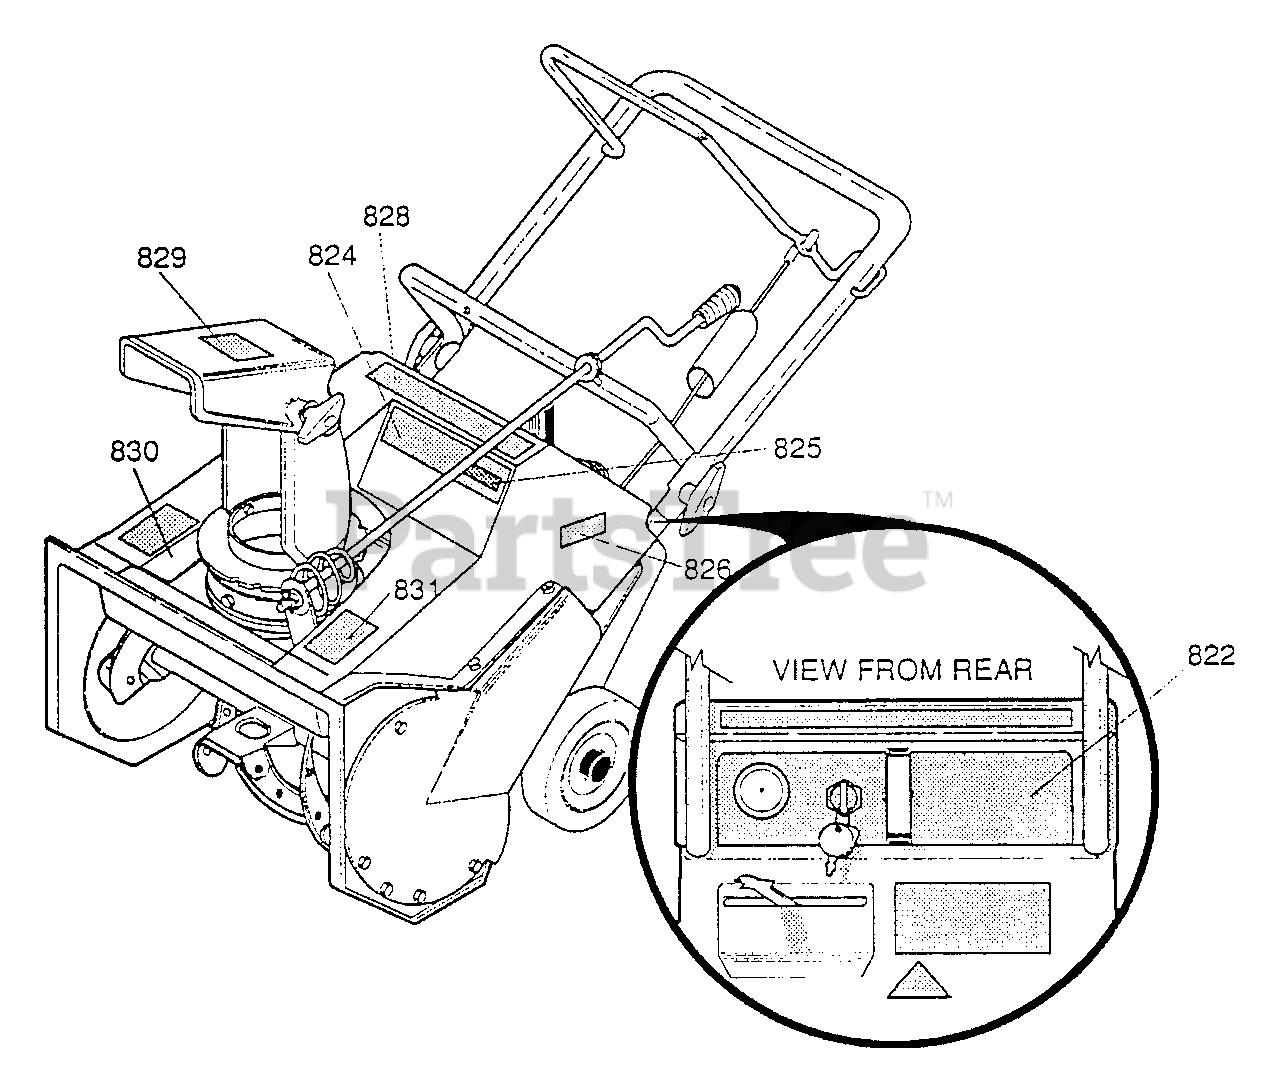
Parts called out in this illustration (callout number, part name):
822	DECAL, CONTROL PANEL
826	DECAL, DANGER MUFFLER
828	DECAL, START INSTR
829	DECAL, DANGER CHUTE
830	DECAL, DANGER CHUTE
831	DECAL. DANGER AUGER
